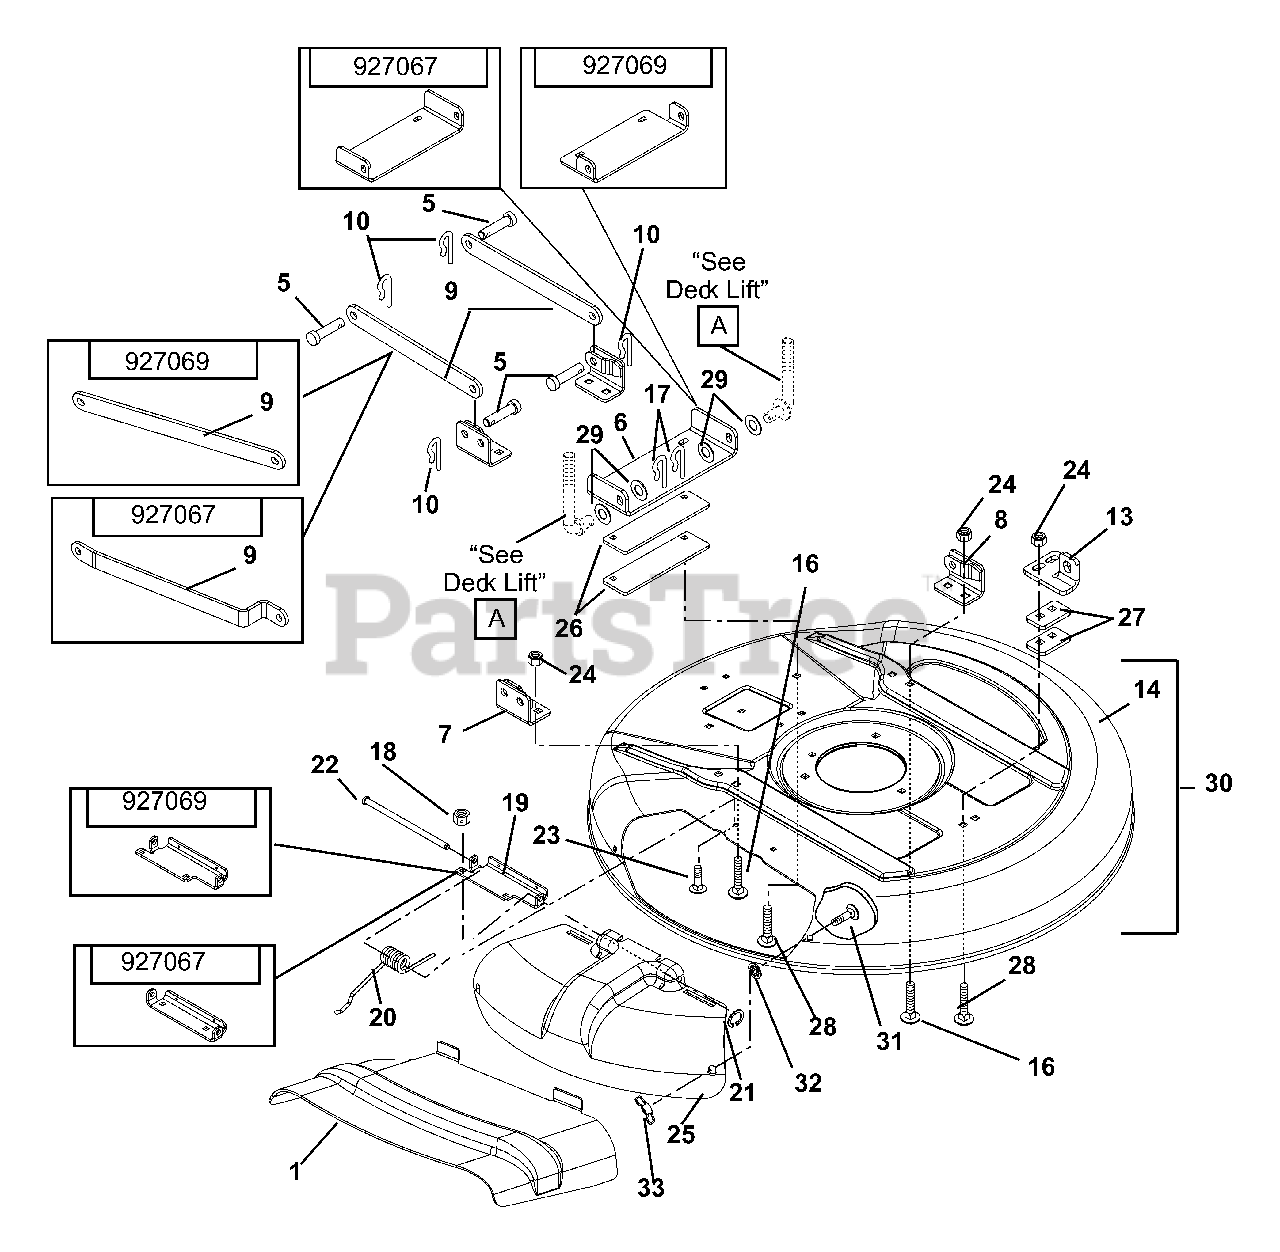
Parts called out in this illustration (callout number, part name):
1	DISCHARGE CHUTE
2	KEY, SQ .25 X .38 X .25
3	BEARING SLINGER
4	BRG-BALL 1.0X2.0X.56 (1641)
5	PIN-CLEV .494X1.00 BLKZC
6	BRKT, REAR HANGER (28" DECK)
6	BRKT, FRONT LIFT (32" DECK)
7	BRKT, 28" DECK STABILIZER
7	WLDMT-DECK LINK (RH)
8	WLDMT-DECK LINK (RH)
8	WLDMT-DECK LINK (LH)
9	STABILIZER, 28" DECK (RH)
9	LINK STABILIZER 32"
10	CLIP, SPRING
11	ASSY-SPINDLE HSG
12	SPACER, 1.001 X 1.25 X 1.76
13	BRKT, FRONT HANGER (28" DECK)
13	BRKT, FRONT LIFT (32" DECK)
14	DECK, 28" RER
14	DECK, RER/SZ 32"
15	SHAFT, 28" AND 32" INPUT
16	BLT-RDHDSQNK .38-16X.75 G5BZ
17	PIN, HAIR, EXT - #16 YWZC
18	NUT-LK-FLG .250-20 PL BLK
19	BRKT, 28" MULCH COVER HINGE
19	BKT, HINGE
20	SPRING, TORSION
21	RG-RTNG-EXT .312X.025
22	PIN, HINGE
23	@BLT-RDHDSQNK .25-20X.75 G5YZ
24	@NUT-LK-TOP-FLG .38-16 YWZC
25	COVER, 28" DECK MULCH
25	MULCH COVER, 32" DECK
26	PLATE, 32" REAR HANGER SPACER
27	PLATE, 32" FRONT HANGER SPCR
28	@BLT-RDHDSQNK .38-16X1.25 BKZC
29	WSHR-FL-STL .518X2.0X.105 YWZC
30	KIT, 28" DECK SERVICE ASSY
30	KIT, 32" DECK SERVICE ASSY
31	BLT-RDHDSQSHK.31-18X.75 GR2 YW
32	NUT-PUSH .312
33	NUT-NYLK WING .312-18 YWZC
